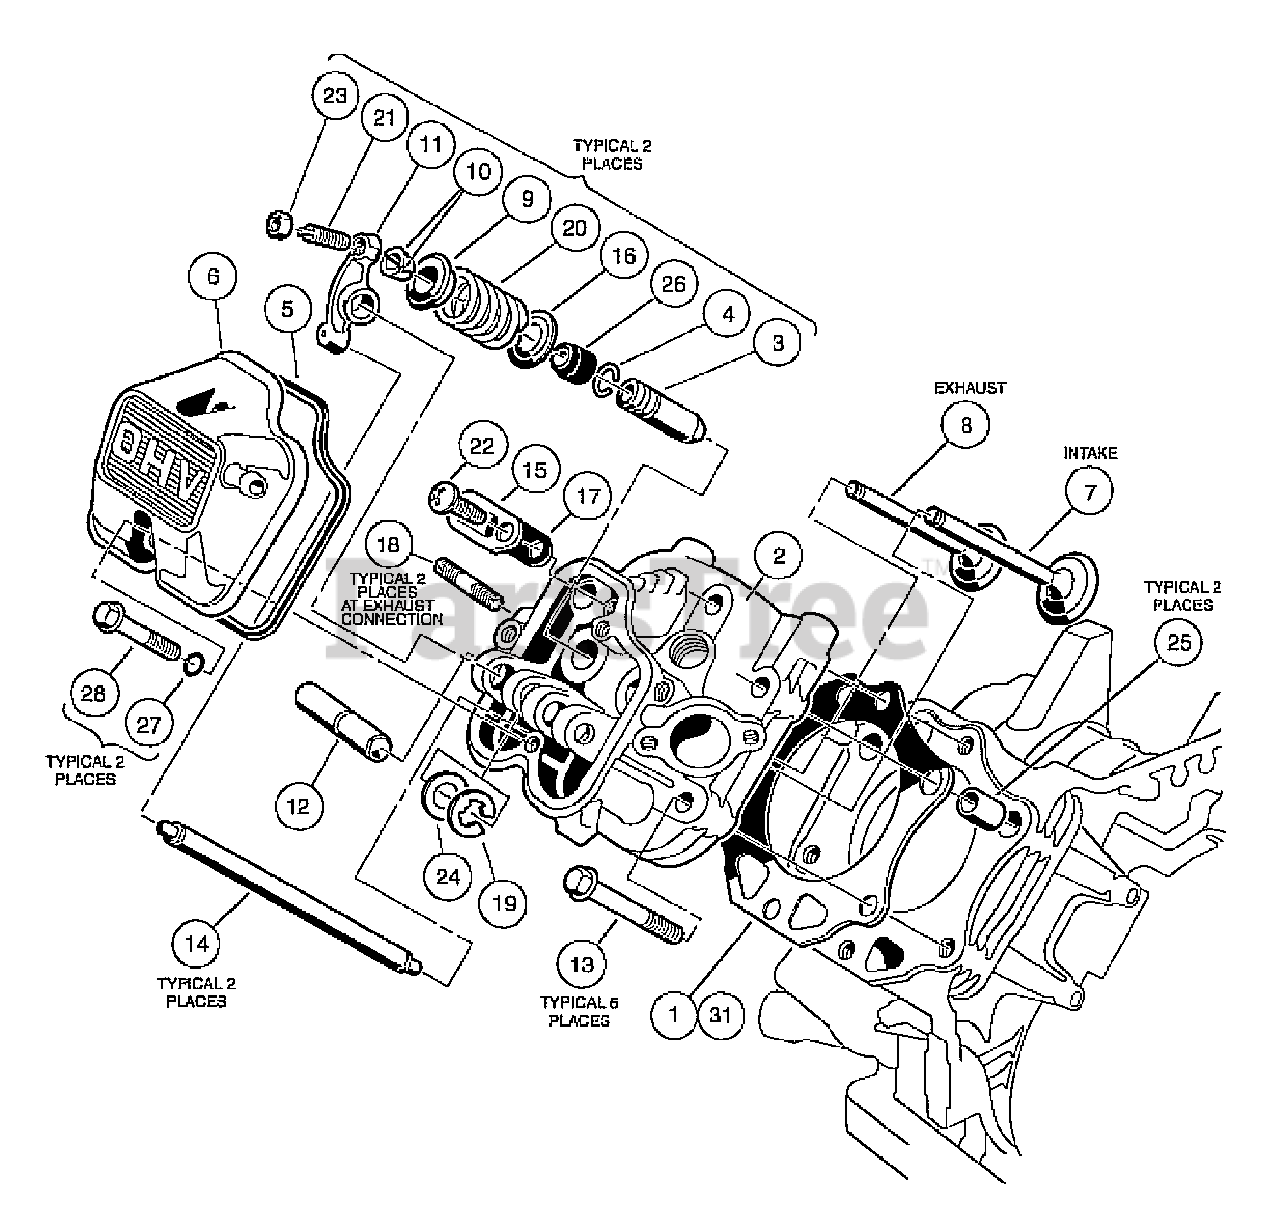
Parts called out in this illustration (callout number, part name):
1	Gasket, Head, FE290
2	Head Assembly, FE290 Cylinder
3	Guide, Valve, Intake
5	Gasket, Rocker Case
6	Case, Rocker
7	Valve, Intake
8	Valve, Exhaust
9	Retainer, Valve Spring
11	Arm, Rocker
12	Shaft, Rocker
13	Bolt, Flange Head, M8 x 1.25 x 45 mm
14	Rod, Push
16	Seat, Spring
18	Stud, Two-Ended, M8-1.25
19	Circlip, Type-E
20	Spring, Engine Valve
21	Screw
23	Nut
24	Washer, 12.1x19x1.B
28	Bolt, 6x35
29	Gasket Kit, Fe290
30	Gasket, Exhaust
31	Gasket, Head, FE290
32	Gasket, Engine To Insulator
33	Gasket, Crankcase Cover
